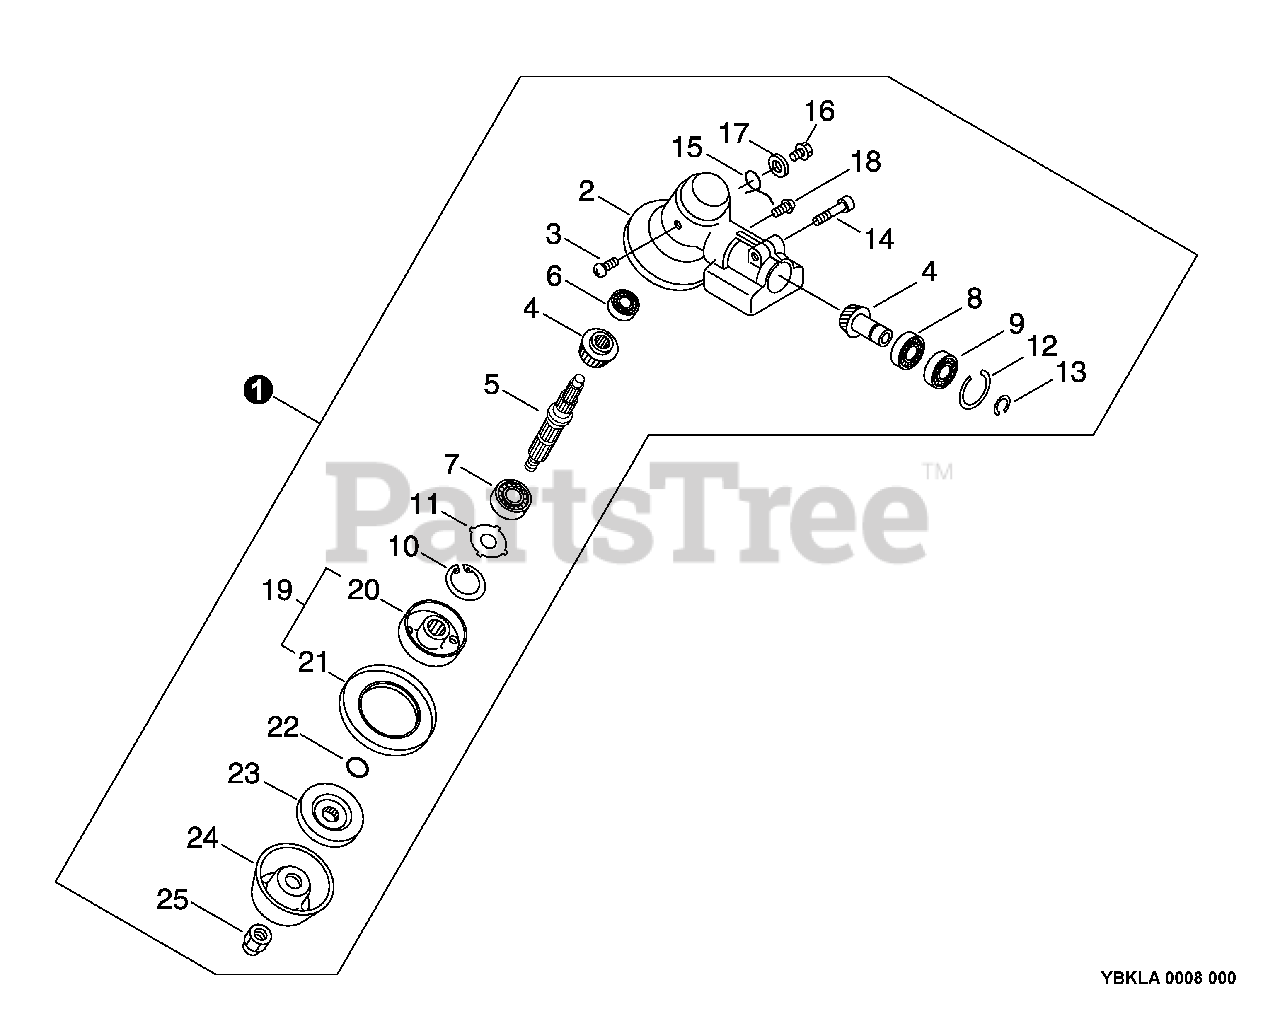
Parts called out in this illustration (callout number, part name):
1	GEAR CASE ASSY
2	CASE, GEAR
3	SCREW - 4X6
4	GEAR SET
5	GEAR - SHAFT
6	BEARING, BALL - 629
7	BEARING, BALL - 6201
8	BEARING, BALL - 6001
9	BEARING, BALL - 6001
10	RING, RETAINING - 32
12	RING, RETAINING - 28
13	RING, RETAINING - 12
14	SCREW - 6X30
16	BOLT - 8X8
17	WASHER - 8
18	SCREW - 5X10
19	BLADE ADAPTER KIT
20	ADAPTOR, BLADE - UPPER
21	GUARD - UPPER
22	O-RING - 12
23	ADAPTOR, BLADE - LOWER
25	NUT - 10
